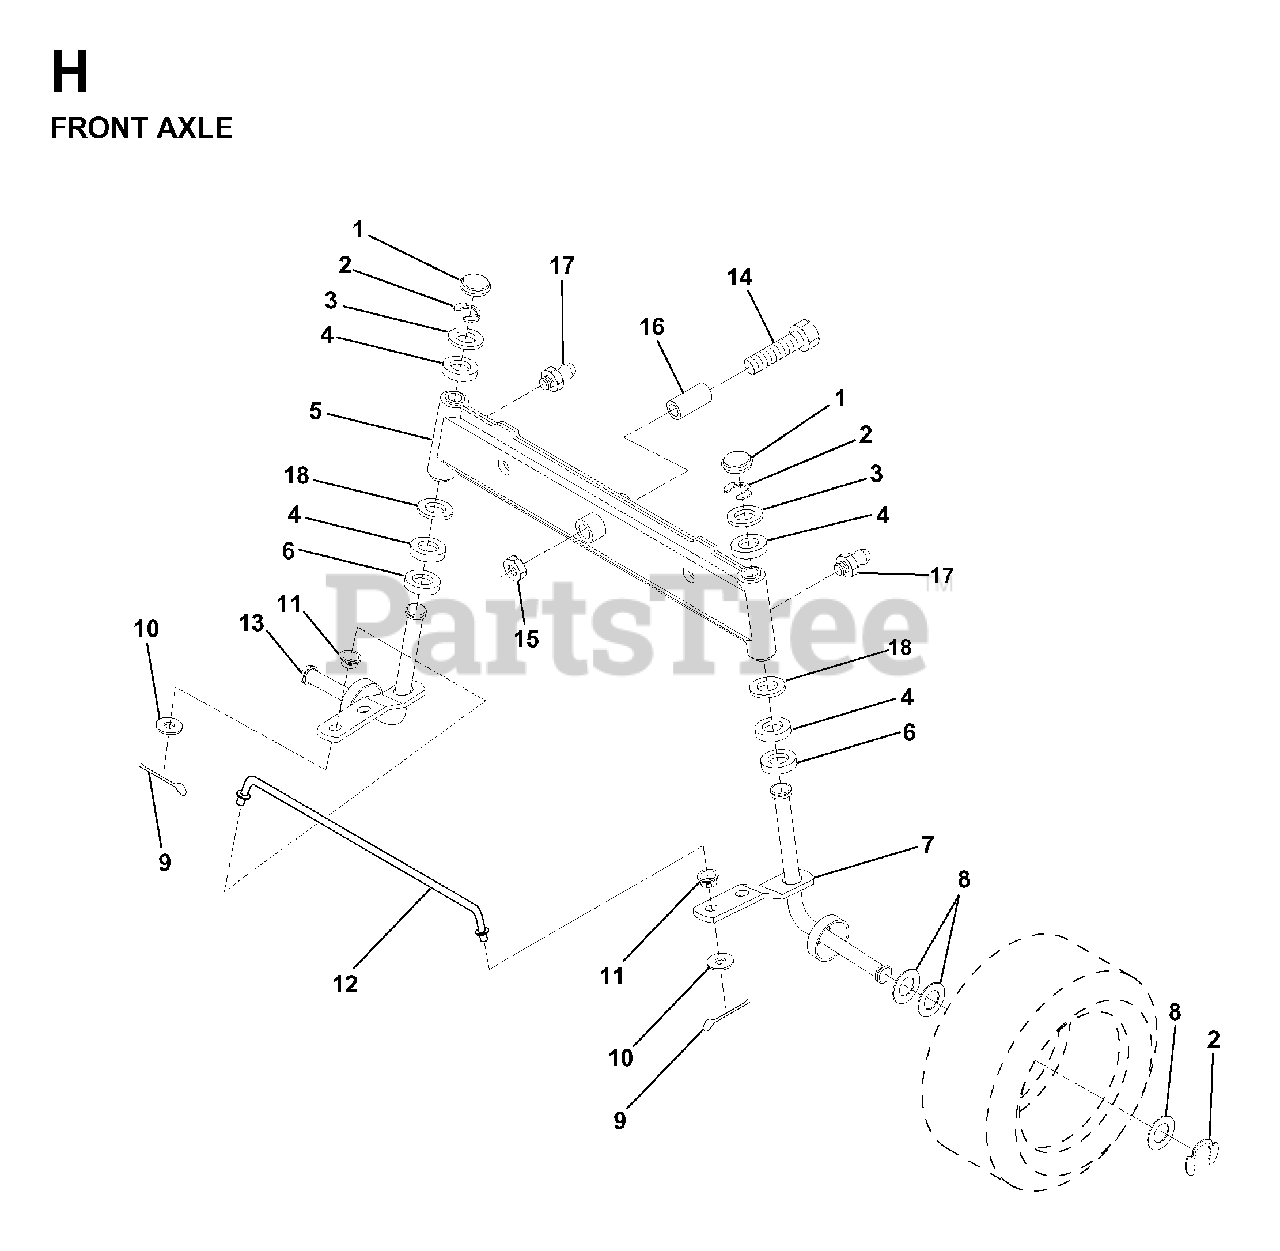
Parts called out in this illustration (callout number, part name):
1	CAP.SPINDLE
2	RING CLIP
4	BRNG T
5	AXLE ASSY
9	COTTER PIN
11	BUSHING.DRAGLINK
12	TIE ROD
13	SPINDLE.ASSEM.LH
14	BOLT.HEX.5/8-11
15	NUT-LOC,FLANGE LT
16	BEARING
17	ZERK M
